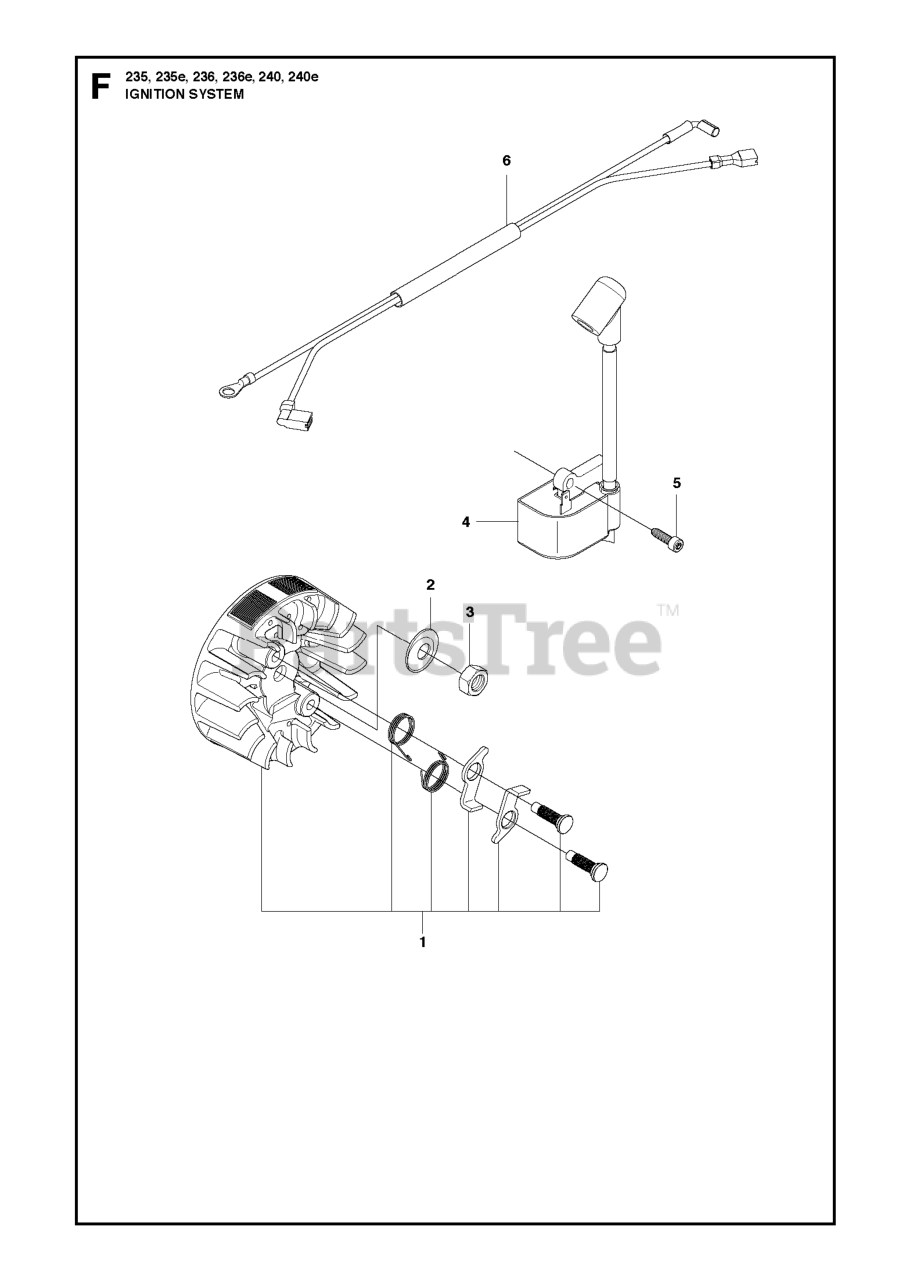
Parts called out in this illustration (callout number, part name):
1	ASSY FLYWHEEL FENGLONG P021
2	WASHER-FLYWHEEL
3	NUT-FLYWHEEL
6	WIRE HARNESS ASSY
